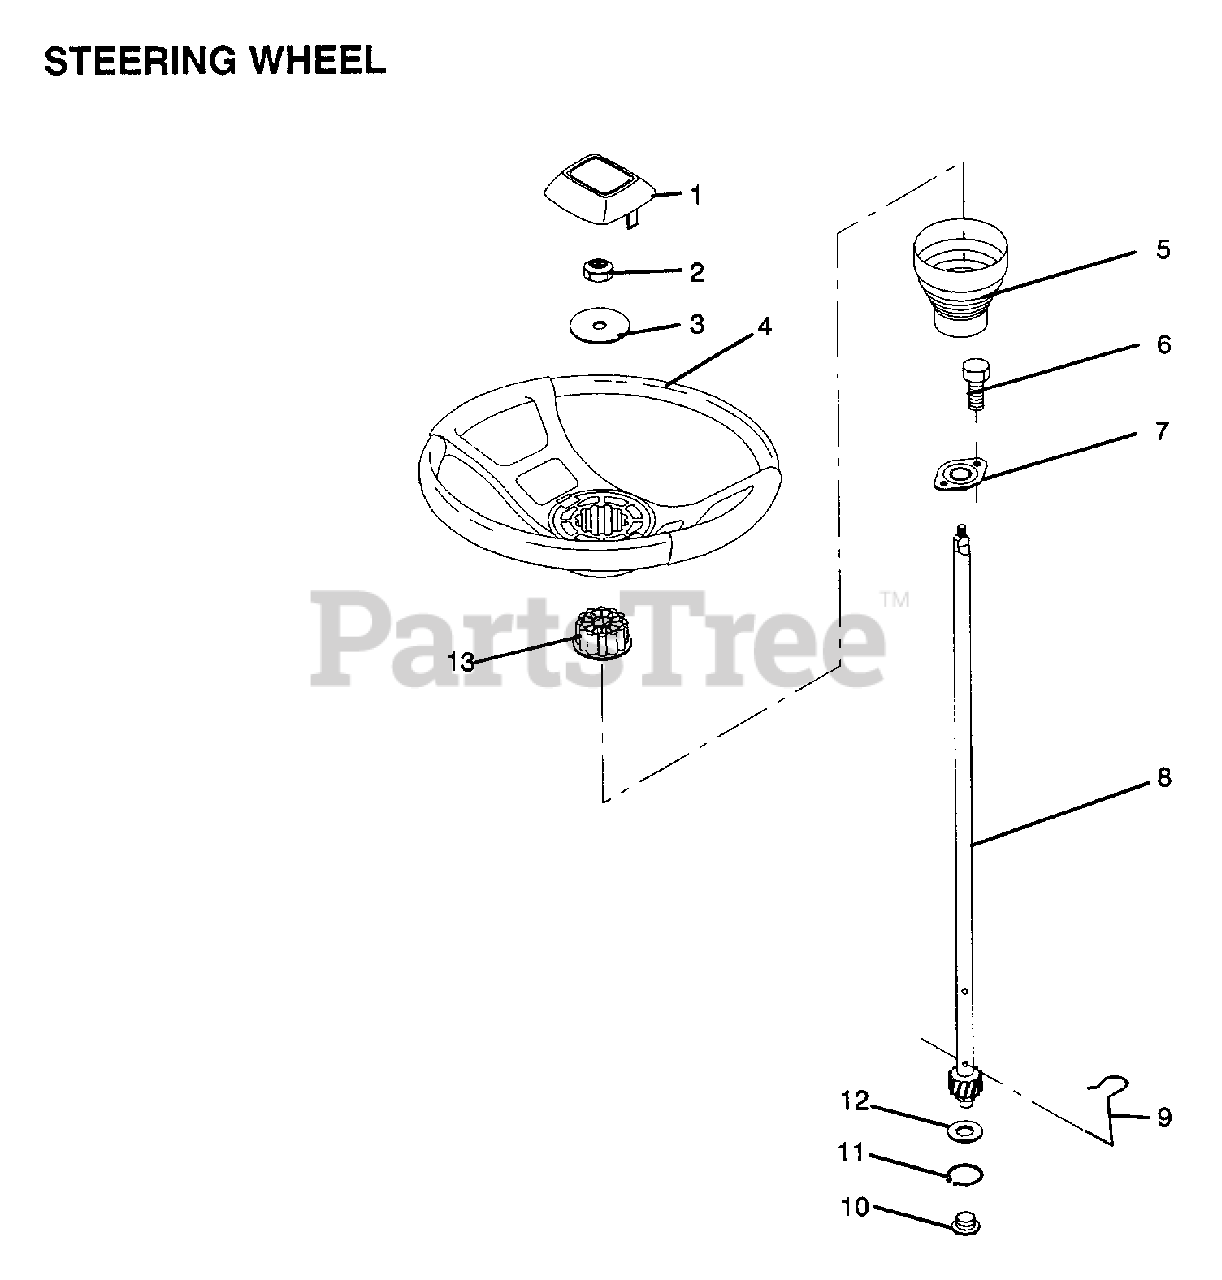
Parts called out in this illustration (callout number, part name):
1	INSERT-WHEEL LT
2	GRIPCO NUT
3	WASHER T
5	SLEEVE STEERING
9	STEERING CLIP
10	BUSHING STEER LWR
11	RING
12	WASHER LT
13	ADAPTER-WHEEL LT
